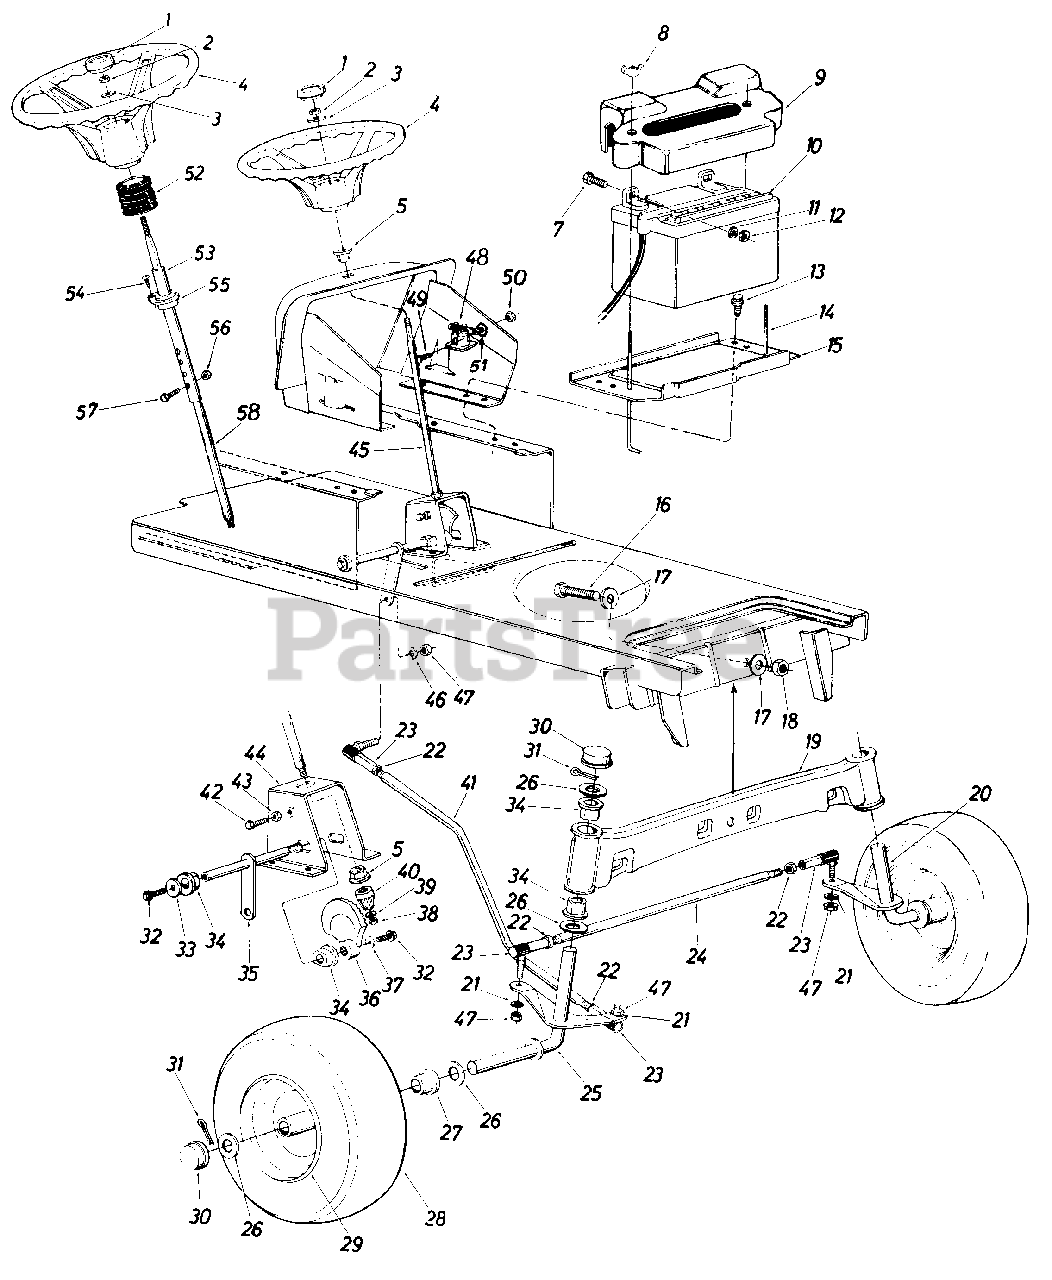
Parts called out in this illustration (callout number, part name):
1	Steering Wheel Cap
2	Hex Cent. L-Nut 5/16-24 Thd.
3	Bell-Wash. 5/16" I.D. x .87" O.D. x .060
4	Steering Wheel
5	Plastic Hex Bearing 5/8" I.D.
7	Hex Bolt 1/4-20 x .62" Lg.
8	Wing Nut Plastic 1/4-20 Thd.
9	Battery Cover
10	12-V Battery
11	L-Wash. 1/4" I.D.
12	Hex Nut 1/4-20 Thd.
13	Hex Thd. Rolling Scr. 1/4-20 x.50" Lg.
14	Battery Hold Down Rod
15	Battery Plate
16	Hex Bolt 5/8-18 x 2.5" Lg.
17	Flat Wash. .66" I.D. x 2.25" O.D. x .17
18	Hex Cent. L-Nut 5/8-18 Thd.
19	Front Pivot Bar Ass'y.
20	Front Axle Ass 'y.-L. H .
21	L-Wash. 3/8" I.D.
22	Hex Jam Nut 3/8-24 Thd.
23	Ball Joint Ass'y.
24	Tie Rod
25	Front Axle Ass 'y.-R . H .
26	Fl-Wash. .780 I.D. x 1.59 O.D.
27	Flange Bearing
28	Front Wheel Ass'y. Comp.
29	Front Wheel Rim Only
30	Dust Cover
31	Cotter Pin 5/32" Dia. x 1.00" Lg.
32	Hex Bolt 3/8-24 x .75" Lg. Grade 5
33	Fl-Wash. 3/8 I.D. x 1.25 O.D. x .090
34	Flange Double "D" Brg. .753 I.D.
35	Steering Arm Shaft Ass'y.
36	Side Gear-Steering
37	Bell-Wash. 3/8" I.D.
38	Hex Cent. L-Nut 5/16-24 Thd.
39	Fl-Wash. 5/16" I.D. x .62 O.D. x .059
40	Pinion Gear-Steering
41	Drag Link
42	Hex Nylon Scr. 3/8-16 x 1.25" Lg.
43	Hex Nut 3/8-16 Thd.
44	Steering Gear Sup. Ass'y.
45	Steering Shaft
46	L-Wash. 3/8" I.D.
47	Hex Nut 3/8-24 Thd.
48	Solenoid
49	Hex Bolt 1/4-20 x .50" Lg.*
50	Hex Sems Nut 1/4-20 Thd.
51	External L-Wash. 1/4" I.D.
52	Steering Bellow
53	Upper Steering Shaft
54	Oval Hd. Cr.-Sunk Scr. #10 x 518" Lg.
55	Fl-Bearing .89" I.D. x 1.36" O.D.
56	Hex L-Nut 1/4-20 Thd.
57	Hex Bolt 1/4-20 x 1.25" Lg.
58	Lower Steering Shaft
